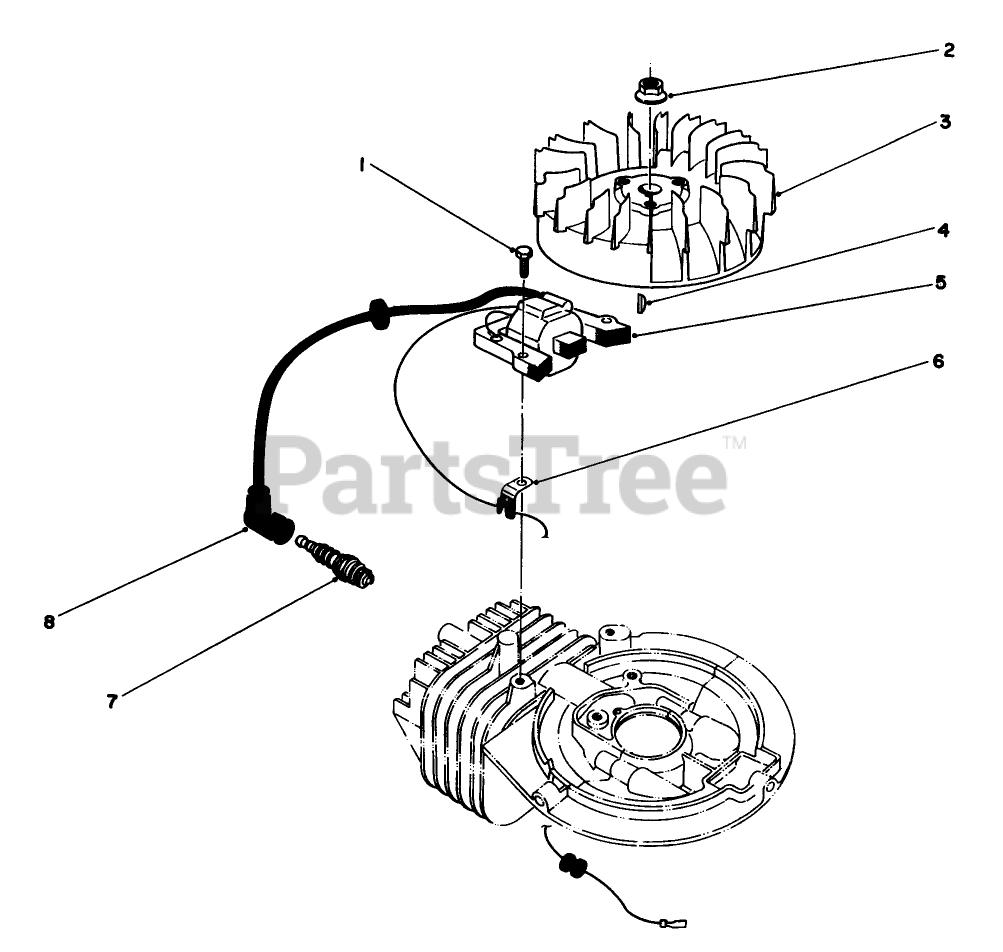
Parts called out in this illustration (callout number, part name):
1	SCREW
3	FLYWHEEL
5	COIL-MAGNETO
6	CLAMP
8	CAP-SPARKPLUG
